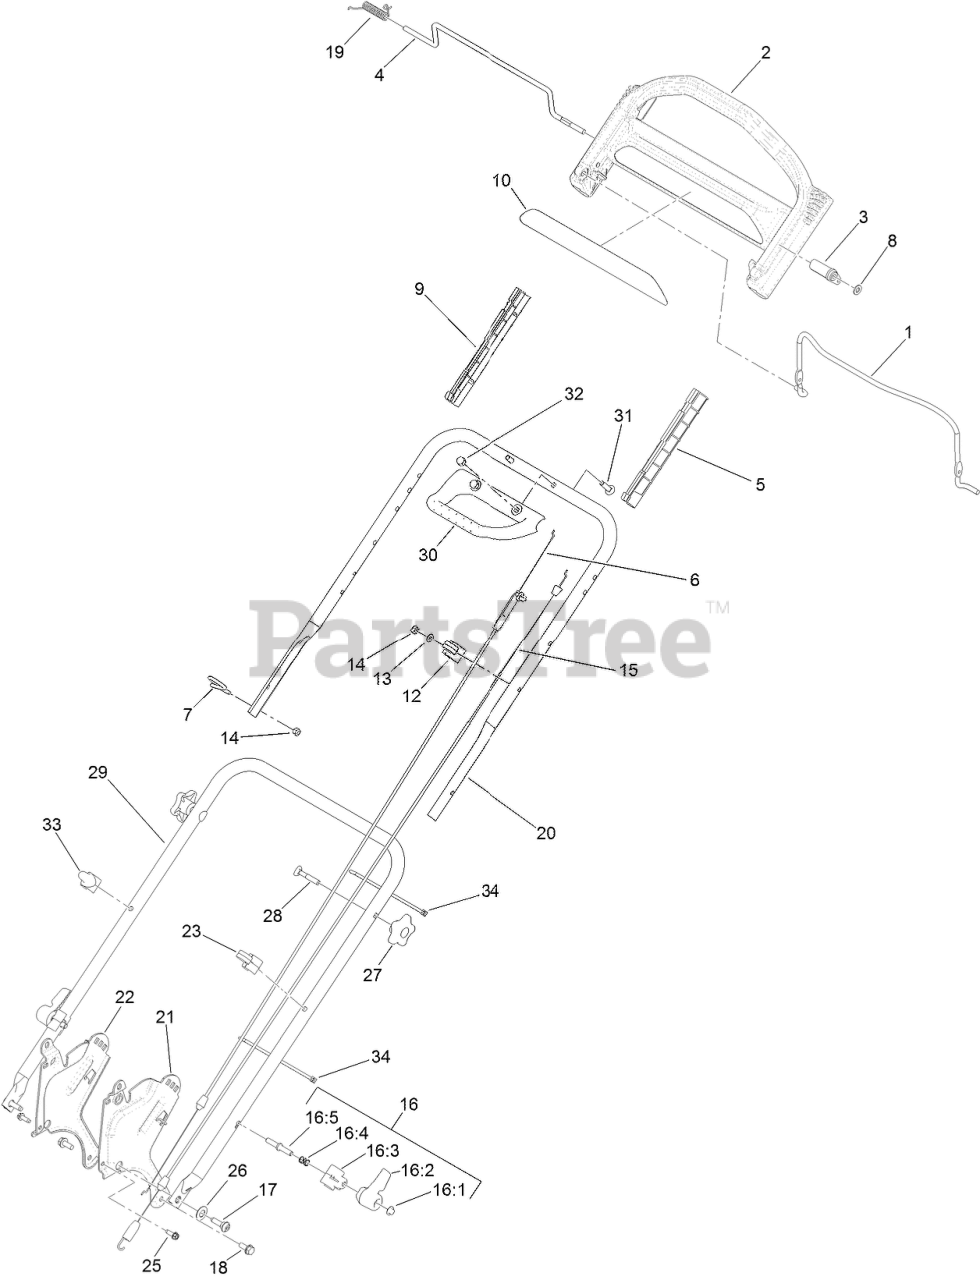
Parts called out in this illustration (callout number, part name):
1	BAIL-BRAKE
2	HANDLE-CONTROL
3	LEVER-TRACTION
4	BAR-CONTROL, TRACTION
5	GUIDE-LH
6	CABLE-BRAKE
7	GUIDE-ROPE
8	WASHER-PLAIN
9	GUIDE-RH
10	DECAL-HANDLE
12	ANCHOR-CABLE
13	WASHER-FLAT
14	NUT-LOCK, NI
15	CABLE-TRACTION
16	QUICK RELEASE ASM
16:1	NUT-PUSH
16:2	LEVER
16:3	ANCHOR-SPRING
16:4	SPRING-COMPRESSION
16:5	ROD-RELEASE
17	SCREW-SHOULDER, BHTF
18	SCREW-HWHTF
19	Spring-Torsion
20	HANDLE-UPPER
21	BRACKET-HANDLE, LH
22	BRACKET-HANDLE, RH
23	GUIDE-CABLE
25	SCREW-HWHTF
26	WASHER-SPRING, CONICAL
27	KNOB-HANDLE
28	SCREW-HANDLE
29	HANDLE-LOWER
30	HANDLE-ASSIST, TRACTION
31	BOLT-CARRIAGE
32	NUT-ACORN
33	GUIDE-ROPE, FLEXIBLE
34	TIE-CABLE
